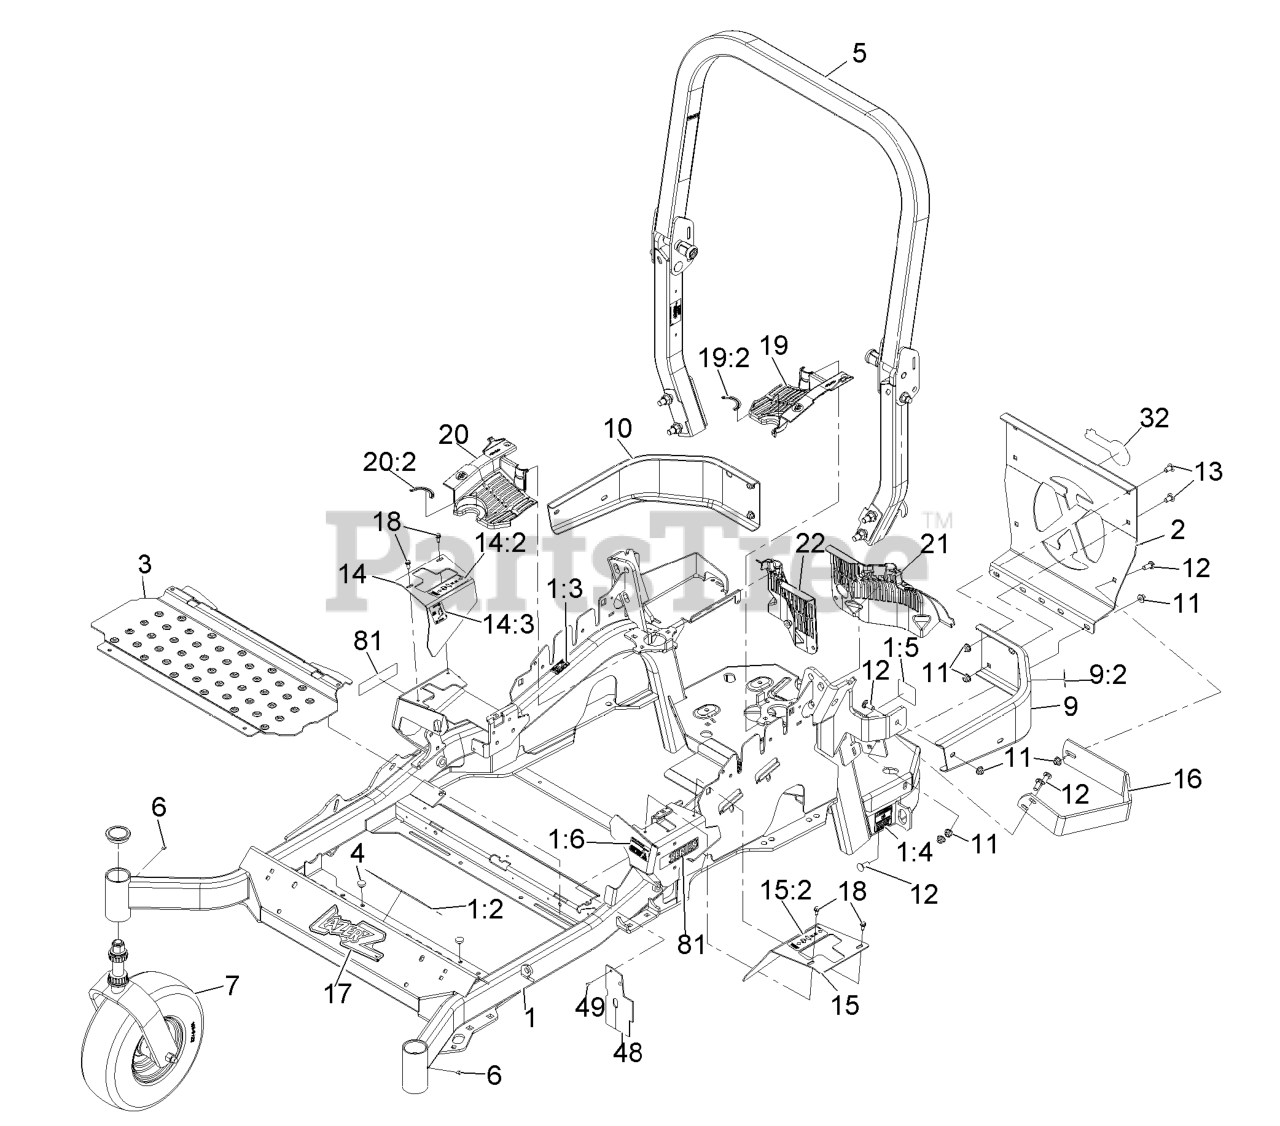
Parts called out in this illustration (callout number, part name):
1	MAIN FRAME ASM
1:2	DECAL-SLOPE
1:3	DECAL-CAUTION
1:4	DECAL-BELT DRIVE
1:5	DECAL-SPARK ARRESTER
1:6	DECAL-FUEL FILL
2	PLATE,REAR GUARD
5	ASM,ROPS SERVICE EXMARK
7	Caster Wheel Asm
9	LH BUMPER ASM
9:2	DECAL-CAUTION
10	BUMPER-RH
11	NUT-HF, NI
12	SCREW-CARR
13	SCREW-CARR
14:2	DECAL-MOTION CONTROL
15	LH MOTION CONTROL COVER ASM
15:2	DECAL-MOTION CONTROL
17	DECAL,LAZER MODEL
18	SCREW-HWH
19	LH HYDRO GUARD ASM
19:2	DECAL-HYDRO OIL
20	RH HYDRO GUARD ASM
20:2	DECAL-HYDRO OIL
21	GUARD-HYDRO, REAR (LH)
22	GUARD-HYDRO, REAR (RH)
48	DEFLECTOR-AIR FLOW
49	RIVET-POP
81	DECAL-X-SERIES
